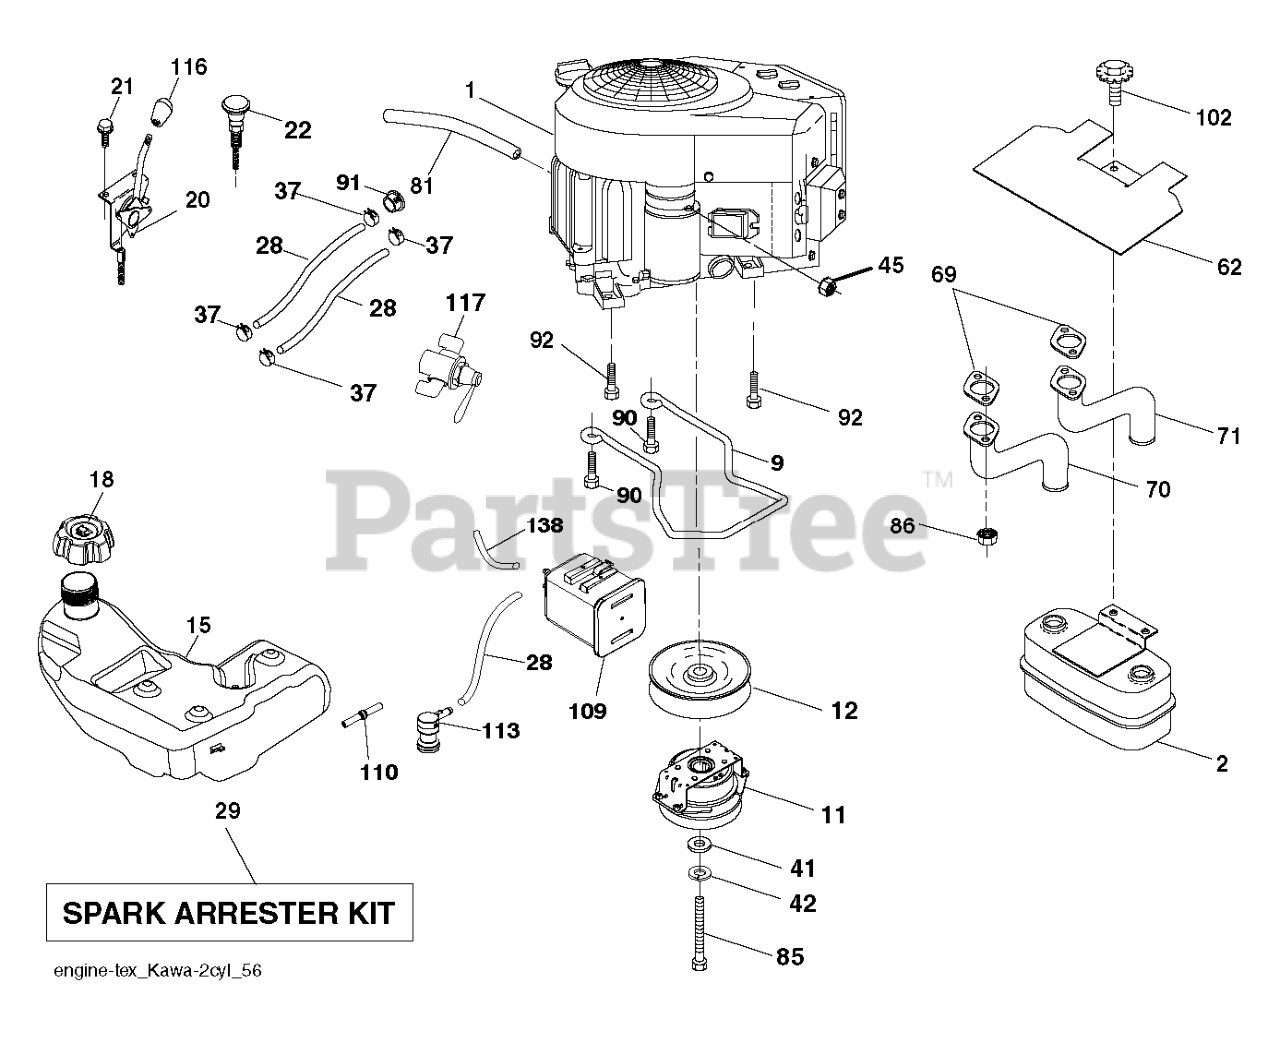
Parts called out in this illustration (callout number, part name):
2	MUFFLER.ASM.TWIN.MNTG.BRACKET
9	KEEPER.BELT.ENG.4.25"2.BLT.431
11	CLUTCH.OGURA.5.0PD.GT1.5A-EH01
12	PULLEY ENGINE
15	TANK.ASM.FUEL.4R.GAL.CARB.17
18	CAP ASSY FUEL 3" GRAY
18	FUEL CAP
20	CONTROL.THROTTLE.PRO.
21	SCREW.#10 X 0.750.BOS
22	CONTROL.CHOKE.ERGO.PUSH-IN.BLA
28	LINE.FUEL.64"REAR.EMIS
29	KIT.SPARK ARRESTOR 794945 B&S
37	HOSE CLAMP
42	LOCKWASHER
45	NUT
62	SHIELD.HEAT.MUFFLER
70	TUBE.EXHAUST.LH.FR961/FR730
71	TUBE.EXHAUST.RH.FR961/FR730
81	TUBE, DRAIN OIL ASM.
85	BOLT.HEX.7/16-20X3.GR5.YELLOW
86	NUT.HEX.FLANGE.TOPLOCK
90	SCREW 3/8-16X1
91	BUSHING.1.375OD
92	SCREW 3/8-16X1
102	SCREW
109	CANNISTER, CARBON
110	VALVE.ASM.ANTI-SLOSH
113	VALVE.SLANT.CARTRDG.90 DEG.TEX
116	RP KNOB SOFT TOUCH
117	VALVE FUEL RESERVE
138	RP PURGE LINE
